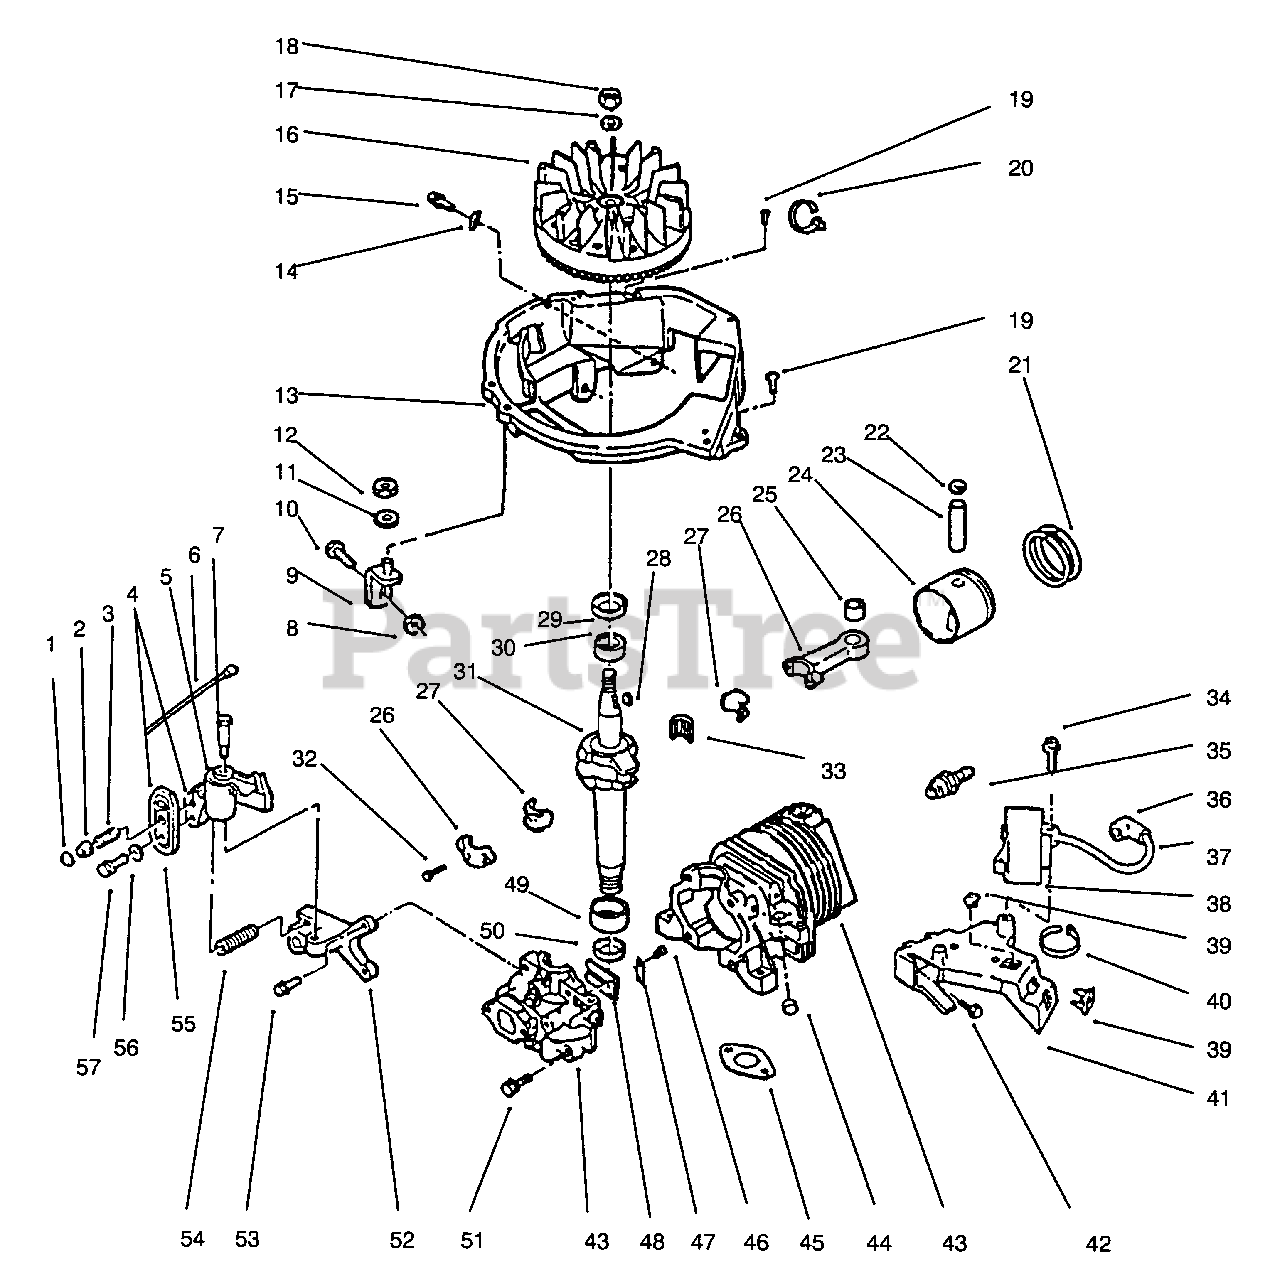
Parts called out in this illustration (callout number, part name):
1	Retainer
2	Actuator-Brake Lever
3	Spring-Cable, Return
4	Switch Assembly (Incl. ref. #1, 6, 20, 56-58)
5	Brake Assembly
6	Wire Lead
7	Bolt-Shoulder
9	Brace Assembly
13	Shroud-Base
14	"J" Clip
16	Flywheel Assembly
17	Washer-Lock
18	Nut-Flywheel
20	Tie Strap
21	Set-Ring
22	Ring-Retaining
23	Pin-Wrist
24	Piston & Connecting Rod Assembly (Incl. Ref. #20,24-27 & 32-33)
25	Bearing Assembly
26	Connecting Rod Assembly (Incl. Ref. #25, 27, 32 & 33)
27	Liner-Split
28	Key-Flywheel
29	Seal-Oil
30	Bearing-Main
31	Crankshaft
33	Set-Needle Bearing
34	Screw
35	Spark Plug
36	Cover-Terminal
37	Wire Lead
38	C.D. Ignition Module (Incl. Ref. #36, 37)
39	Grommet
40	Tie Strap
41	Bracket-C.D.
43	Cylinder & Crankcase Cover Assembly (Incl. Ref. #46-48,51& 58)
45	Gasket-Exhaust
47	Plate-Reed
49	Bearing-Main
50	Seal-Oil
52	Bracket-Brake
54	Spring-Brake
55	Case Assembly
56	Washer
57	Screw
